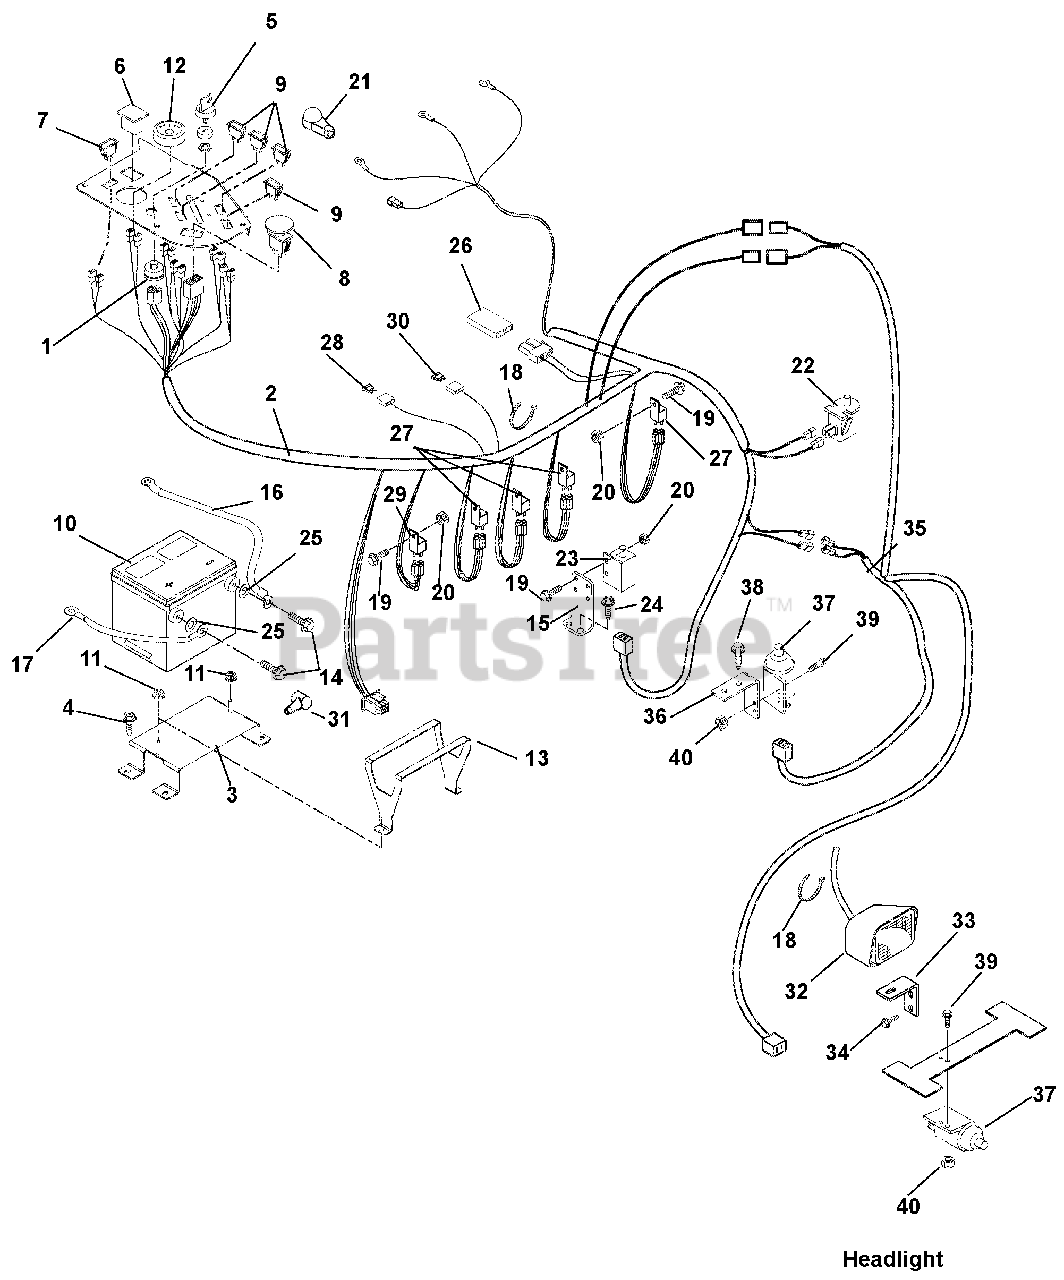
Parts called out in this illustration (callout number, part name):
1	Switch, Ignition
2	Harness, Wiring, PM200 Horizontal Liquid Cooled
3	Weldment, Battery Support
4	Screw, Tapping .38-16 x .75 Hex Washer Head
5	Key, with Cap
6	Hour Meter
7	Switch, Light
8	Switch, Clutch with Retainer Ring
9	Light, Indicator
10	Battery, Group 70-540 CCA
11	Nut, Locking Top Flange .31-18
12	Gauge, Temperature
13	Bracket, Battery Hold-Down
14	Bolt, Hex .25-20 x .75 Grade 5
15	Mount, Safety Switch
16	Positive Cable w/Boots
17	Cable, Negative Battery
18	Cable Tie
19	Screw, Machine 10-24 x .75 Hex Washer Head
20	Nut, Locking Nylon 10-24 with Insert
21	Boot, Terminal, Red
22	Switch, Snap Mounting (N.O.) (Included with Seat)
23	Switch, Single Pole
24	Screw, Tapping .25-20 x .50 Hex Washer Head
25	Washer, Flat Steel .406 x 1.00 x .083
26	Diode, Connector Shell
27	Relay (Included with Harness)
28	Fuse, 20 Amp Blade
29	Pre-Heat Timer (Included with Engine)
30	Fuse, ATO 60 Amp (Included with Harness)
31	Battery Terminal Boot, Red (Included with cable)
32	Headlight
33	Bracket, Headlight Mounting
34	Screw, Tapping, .38-16 x .50 Hex Washer Head
35	Harness, Wire Adapter, PM200 CE
36	Switch, Mount
37	Switch, Double Pole (N.O./N.O.) with Cover
38	Screw, Tapping .31-18 x .50 Hex Washer Head
39	Screw, Machine 10-24 x .75 Hex Washer Head
40	Nut, Locking, Nylon 10-24 with Insert
